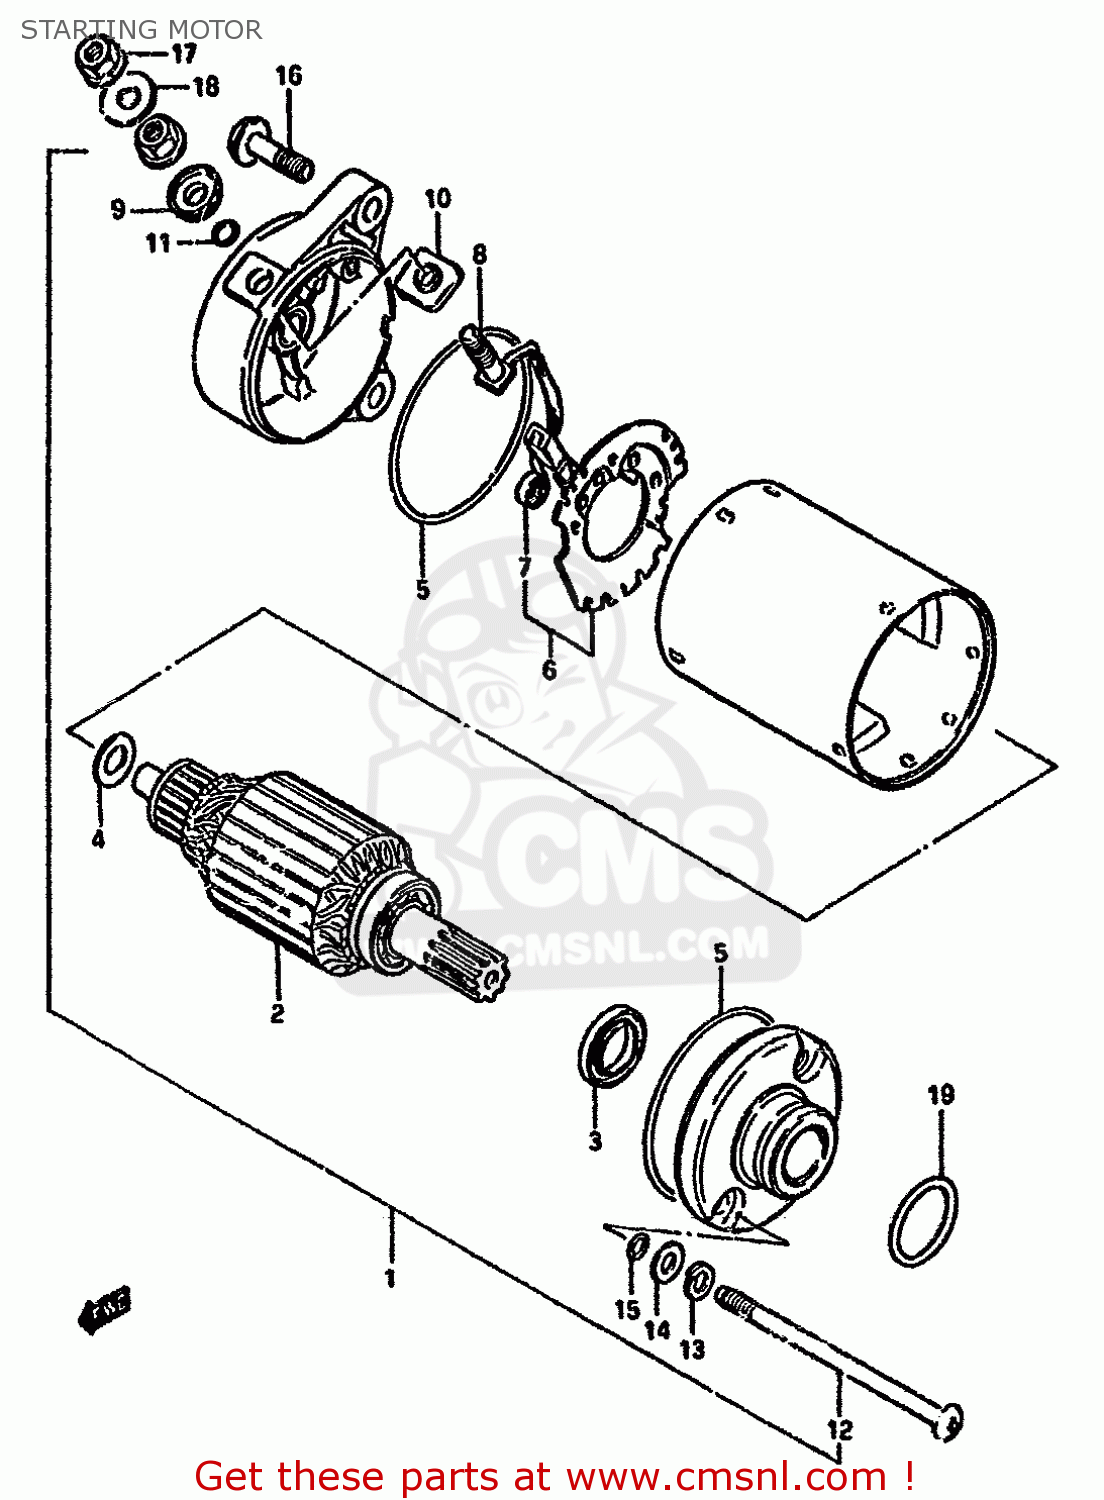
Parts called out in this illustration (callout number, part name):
1	MOTOR ASSY,STARTING
2	ARMATURE
3	SEAL,OIL
4	SHIM,ARMATURE
5	O RING
6	HOLDER,BRUSH
7	SPRING
8	BRUSH SUB ASSY,STARTING MOTOR
9	BUSHING
10	BUSH,B
11	O RING
12	BOLT
13	WASHER,LOCK
14	WASHER
15	O RING
16	BOLT
17	NUT
18	WASHER (6.7X16X1.8)
19	O RING(D:3,ID:24.5)
